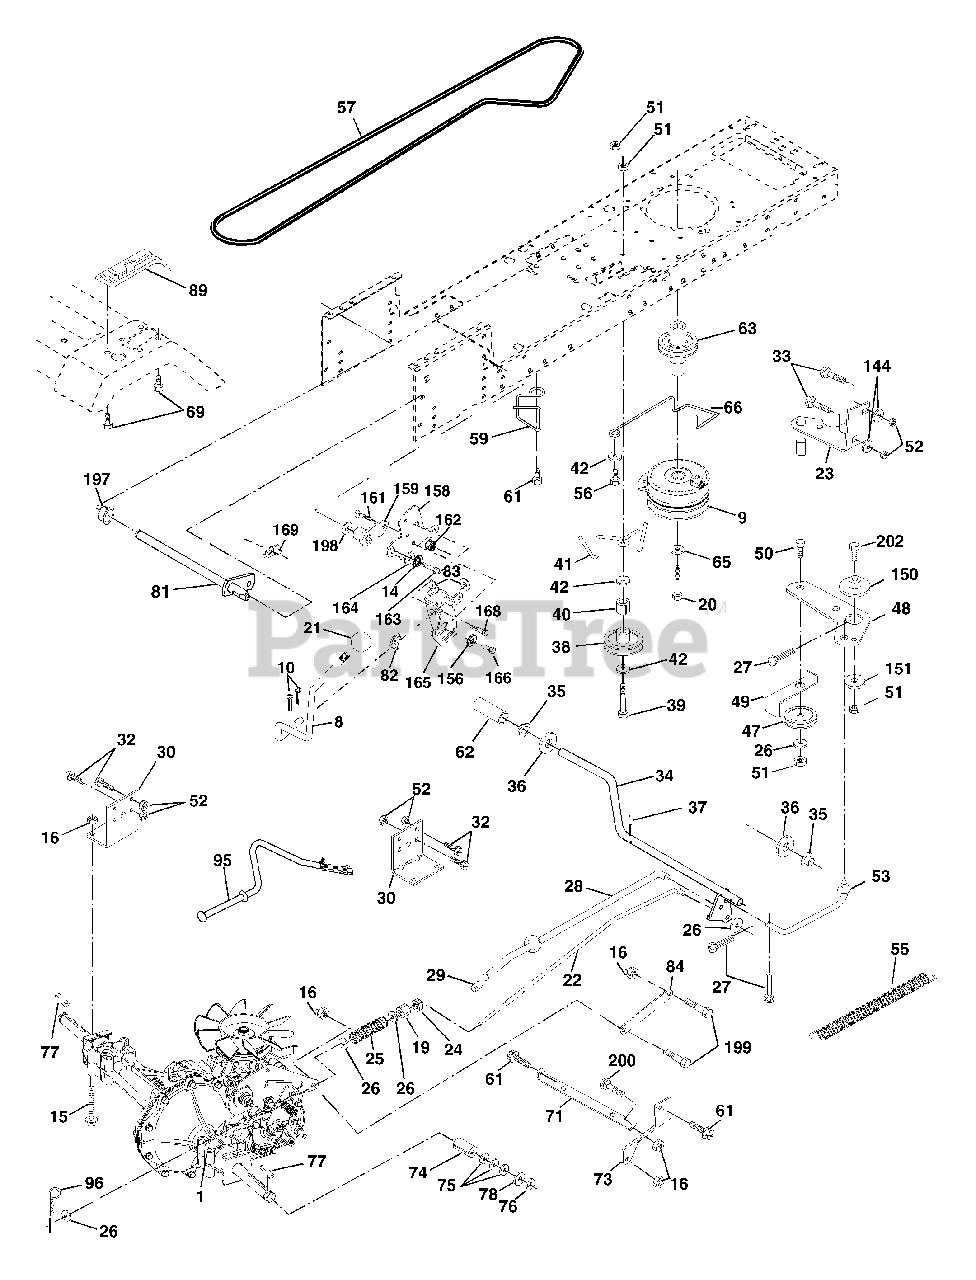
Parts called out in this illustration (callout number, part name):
8	Rod Shift Fender
9	Clutch Electric
10	Pin Cotter 1/8 x 1 CAD
14	Washer Lock Hvy Helical
15	Bolt Hex Flghd 5/16-18 Gr. 5
16	Nut Lock Hex W/Ins. 5/16-18 Unc
19	Nut Lock Hex W/Wsh 3/8-16 Unc
20	Bolt, Hex 7/16-20 x 4-1/4
21	Knob Deluxe
22	Rod, Brake Hydro
23	Bracket Asm. Anti-Rot EVX
24	Locknut
25	Spring, Brake Rod
26	Washer
27	Pin Cotter 1/8 x 3/4 CAD.
28	Rod, Parking Brake
29	Cap, Parking Brake
30	Bracket, Transaxle
32	Bolt Hex Hd 5/16-18 Unc x 3/4
33	Bolt Carriage 5/16-18 UNC x 3/4
34	Shaft, Foot Pedal
35	Bearing, Nylon
36	Washer
37	Pin, Roll
38	Pulley, Idler, Flat
39	Bolt
40	Spacer Split
41	Keeper, Belt Idler Fool-Proof
42	Washer 13/32 x 13/16 x 12 Gauge
47	Pulley, Idler, V-Groove
48	Bellcrank Clutch Grnd Drv Stl
49	Retainer, Belt
50	Bolt
51	Nut
52	Nut Crown Lock 5/16-18
53	Link, Clutch
55	Spring, Return, Clutch
56	Bolt
57	V-Belt, Ground Drive
59	Keeper, Center Span
61	Screw 3/8-16 x 3/4
62	Cover, Pedal
63	Pulley, Engine
65	Washer
66	Keeper Belt Engine Hydro
69	Screw Hexwsh Hi-Lo 1/4-1/2UNC
71	Strap Torque Lh Hydro
73	Strap Torque Rh Hydro
74	Spacer, Axle
75	Washer 25/32 x 1-1/4 x 16 Ga.
76	E-Ring
77	Key, Square
78	Washer 25/32 x 1-5/8 x 16 Ga.
81	Shaft Asm. Cross Hydro
82	Spring Torsion T/A
83	Washer 17/32 x 3/4 x 16 Ga.
84	Link Transaxle
89	Console, Shift
95	Control Asm. Bypass Hydro
96	Retainer Spring 1" Zinc/Cad
144	Washer 11/32 x 5/8 x 16 Ga.
150	Bushing Bellcrank Grd Drive
151	Washer 13/32 x 2 x 10 Ga.
156	Washer Srrted 5/16ID x 1.125
158	Bracket Shift Mount
159	Hub Tapered Flange Shift Lt
161	Bolt Rdhd Sqnk 1/4-20 x 3/4 Gr. 5
162	Nut Crownlock 1/4-20 Unc
163	Bolt Hex Fin 1/4-20 Unc x 1 Gr. 5
164	Washer 5/8 x .281 x 10 Ga
165	Bracket Pivot Lever
166	Screw 5/16-18 x 5/8
168	Bolt Shoulder 5/16-18 x .561
169	Plate Fastening Lt\
197	Nyliner Snap-In 5/8" ID
198	Washer Nyliner 7/8 ID x .105
199	Bolt Shoulder 5/16-18 Unc
200	Bolt Rdhd Sqnk 5/16-18 UNC x 1
202	Bolt Carr Sh 3/8-16 x 1-1/2 Gr.5
